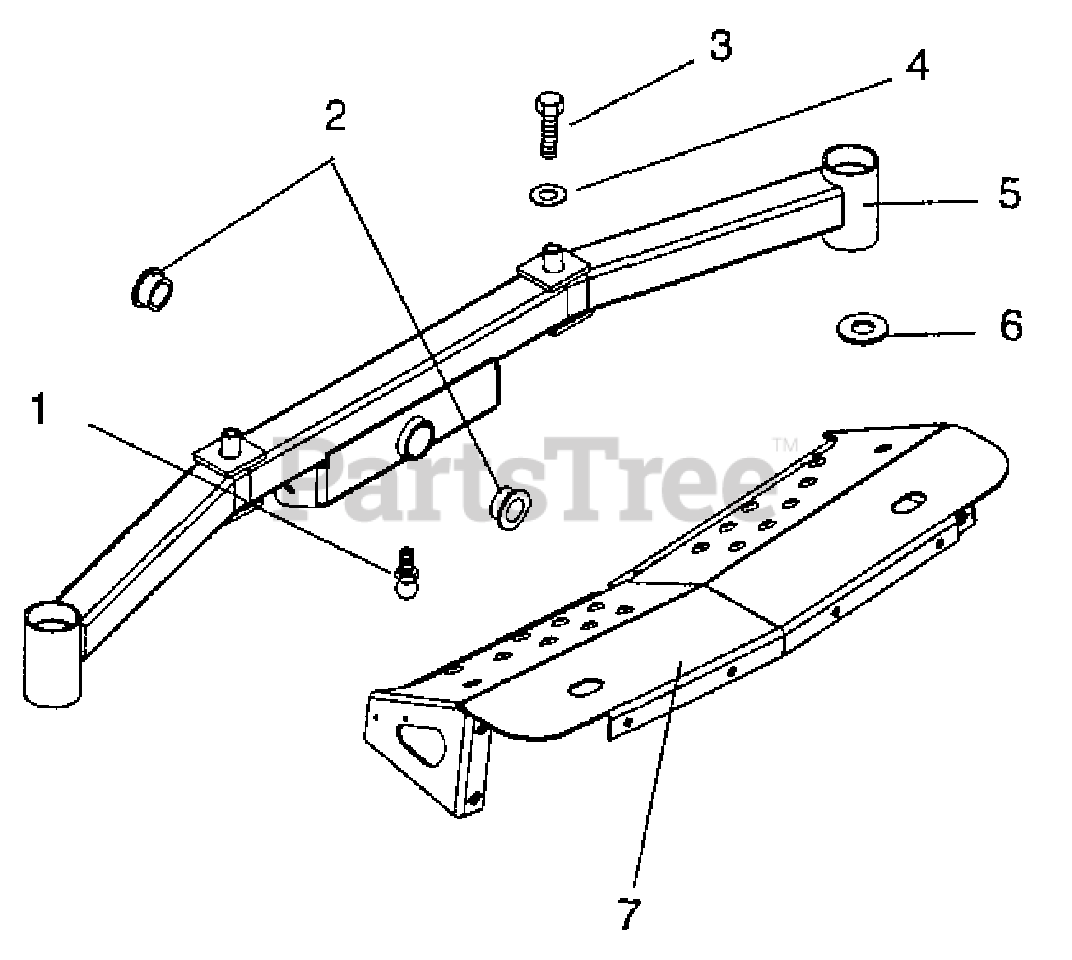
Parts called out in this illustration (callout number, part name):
1	Lube Fitting
2	Nylon Flange Bushing
3	1/2" x 1'' Hex Bolt
4	33/64" Flat Washer
5	Front Axle Assembly
6	Bearing Seal
7	Axle Cover
